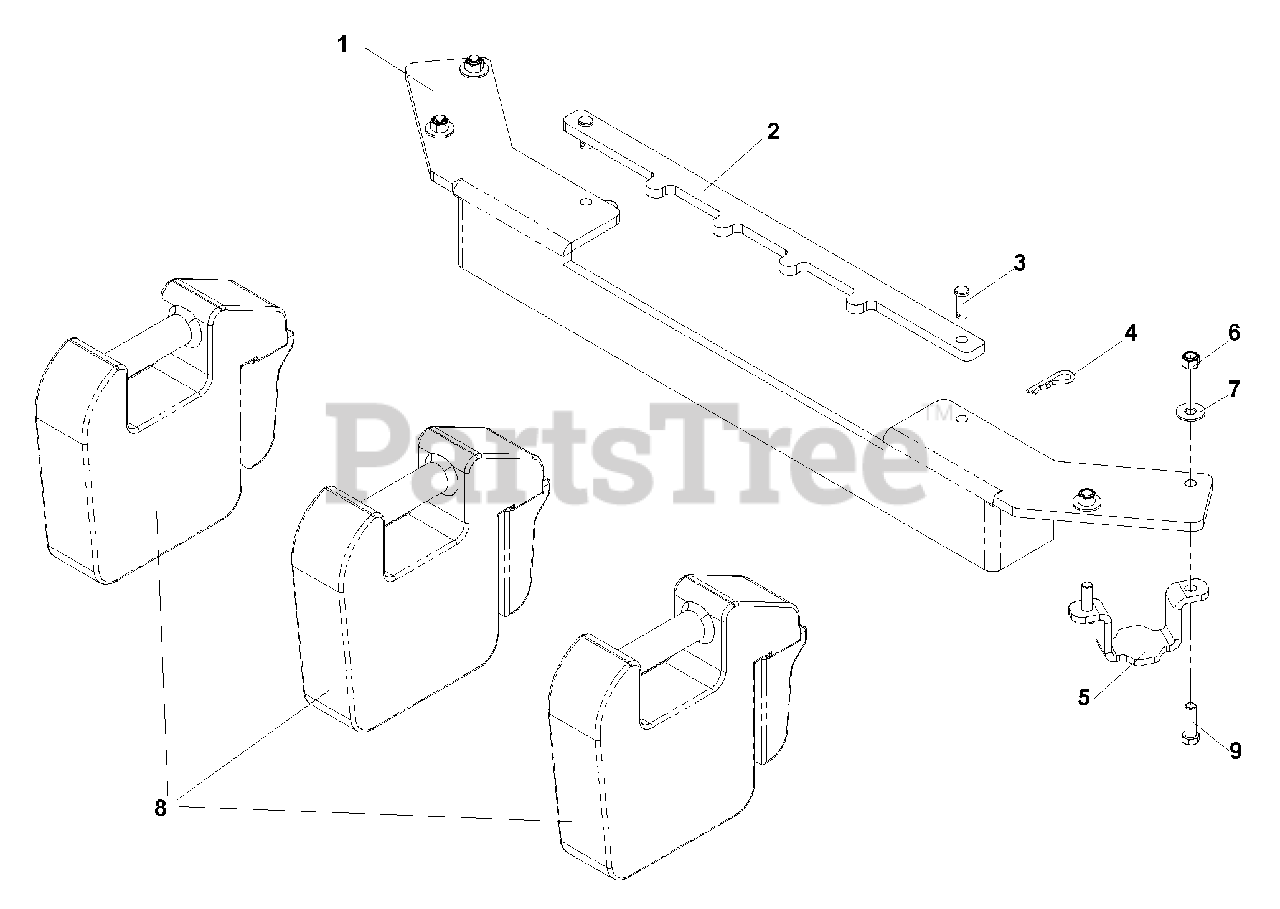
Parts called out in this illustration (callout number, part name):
1	WEIGHT BAR, FRONT
2	HOLD DOWN, WEIGHT BAR
3	CLEVIS PIN
4	SPRING RETAINER
5	WEIGHT KEEPER
6	NUT, 3/8, NYLOC
7	WASHER, 3/8
8	CAST COUNTERWEIGHT
9	HCS, 3/8-16 x 1 1/4,
